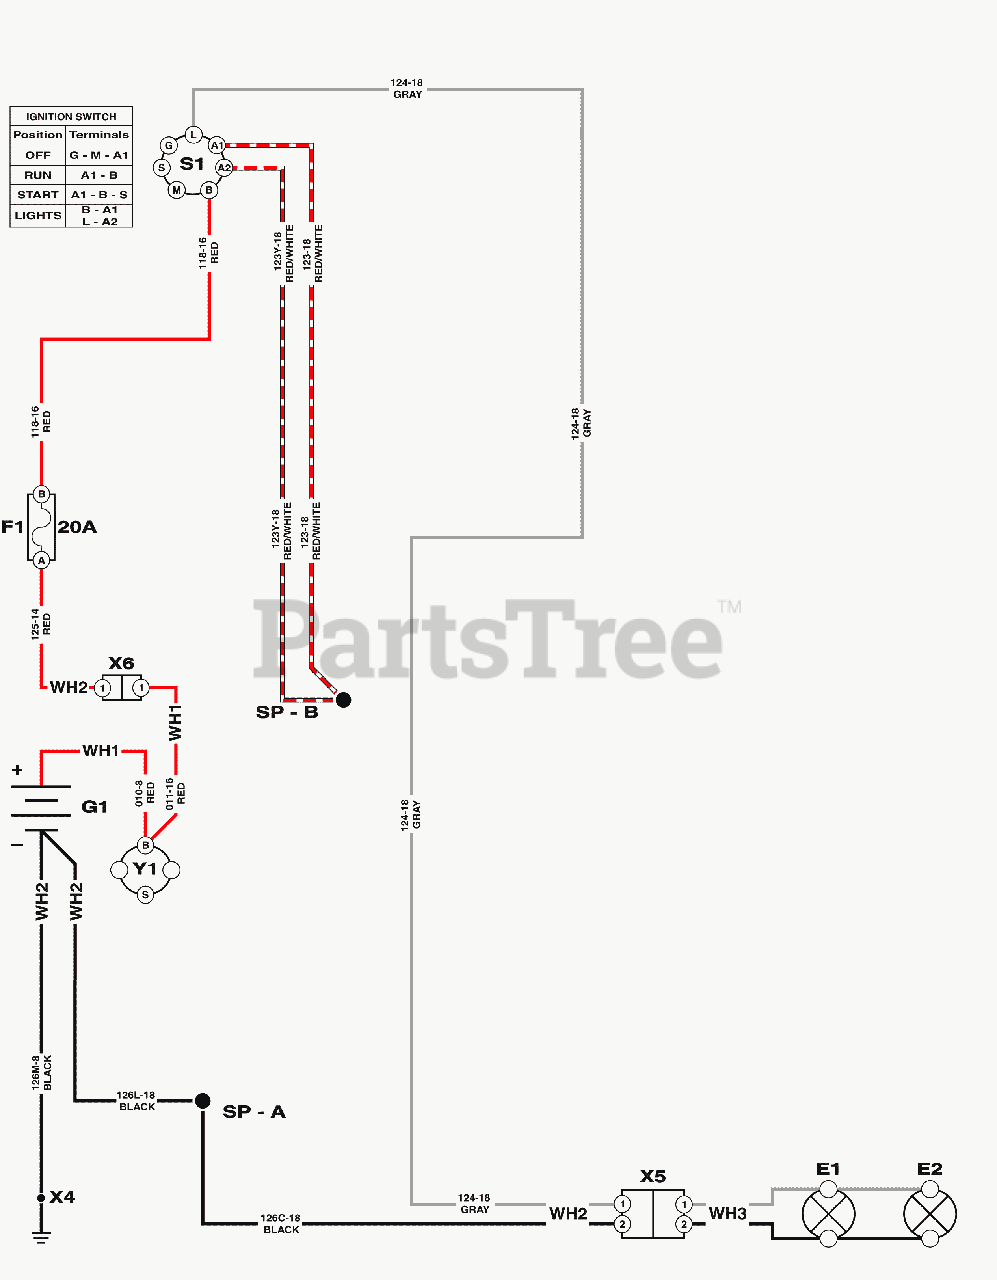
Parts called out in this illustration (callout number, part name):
E1	HEADLIGHT, Left
E2	HEADLIGHT, Right
F1	FUSE, Wiring Harness
G1	BATTERY, 12 Volt, 230 CCA
S1	SWITCH, Ignition
WH1	HARNESS, Battery, Solenoid
WH2	HARNESS, Main
WH3	HARNESS, Headlight
X4	CHASSIS GROUND POINT
X5	CONNECTOR, Main Harness to Headlight Harness
X6	CONNECTOR, Battery Solenoid Harness to Main Harness
Y1	SOLENOID
